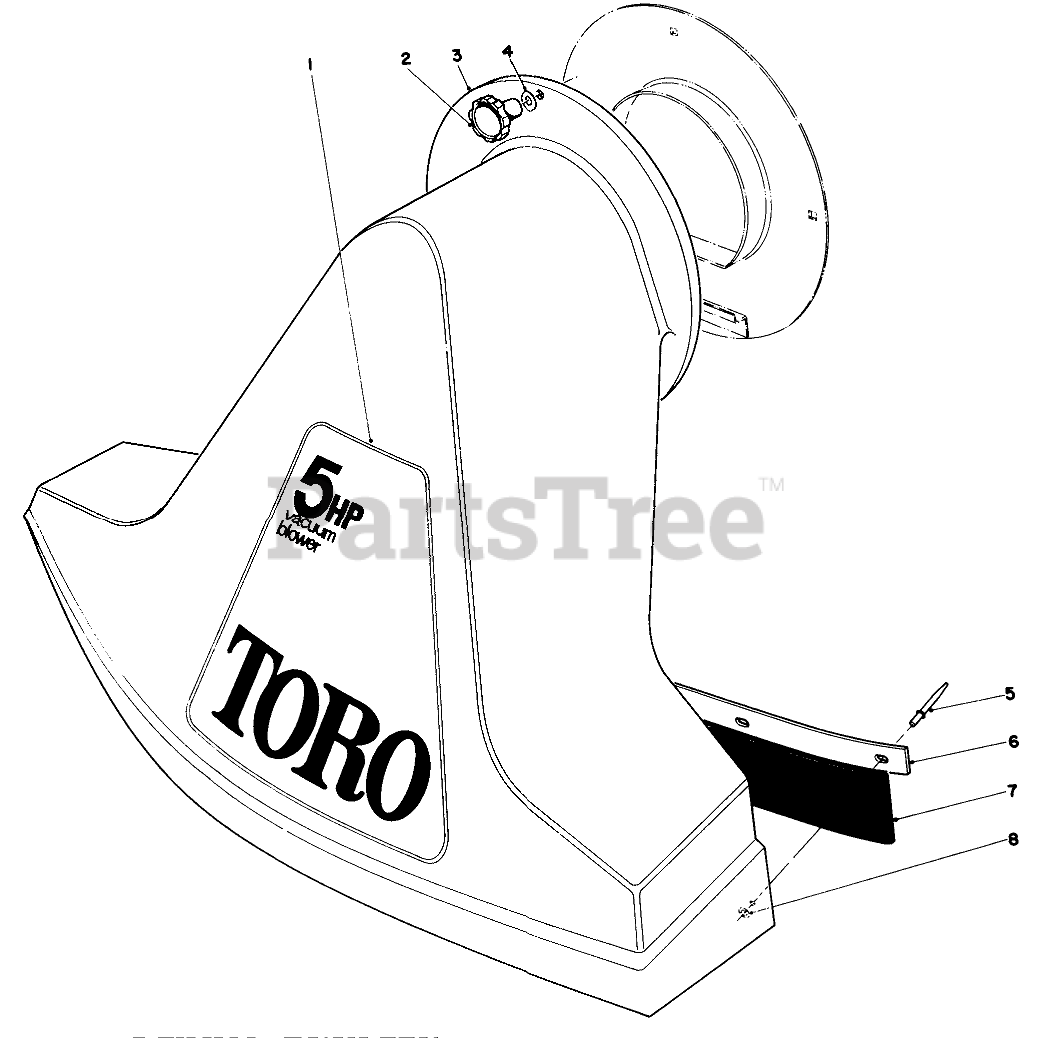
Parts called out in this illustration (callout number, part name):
1	Decal-Toro Model No. 62912
3	Snout Assembly (Incl. Ref. #5-8)
4	Washer
5	POP RIVET 3/16X.375LG
6	Clamp-Flap
7	FLAP-RUBBER
8	WASHER-FLAT
